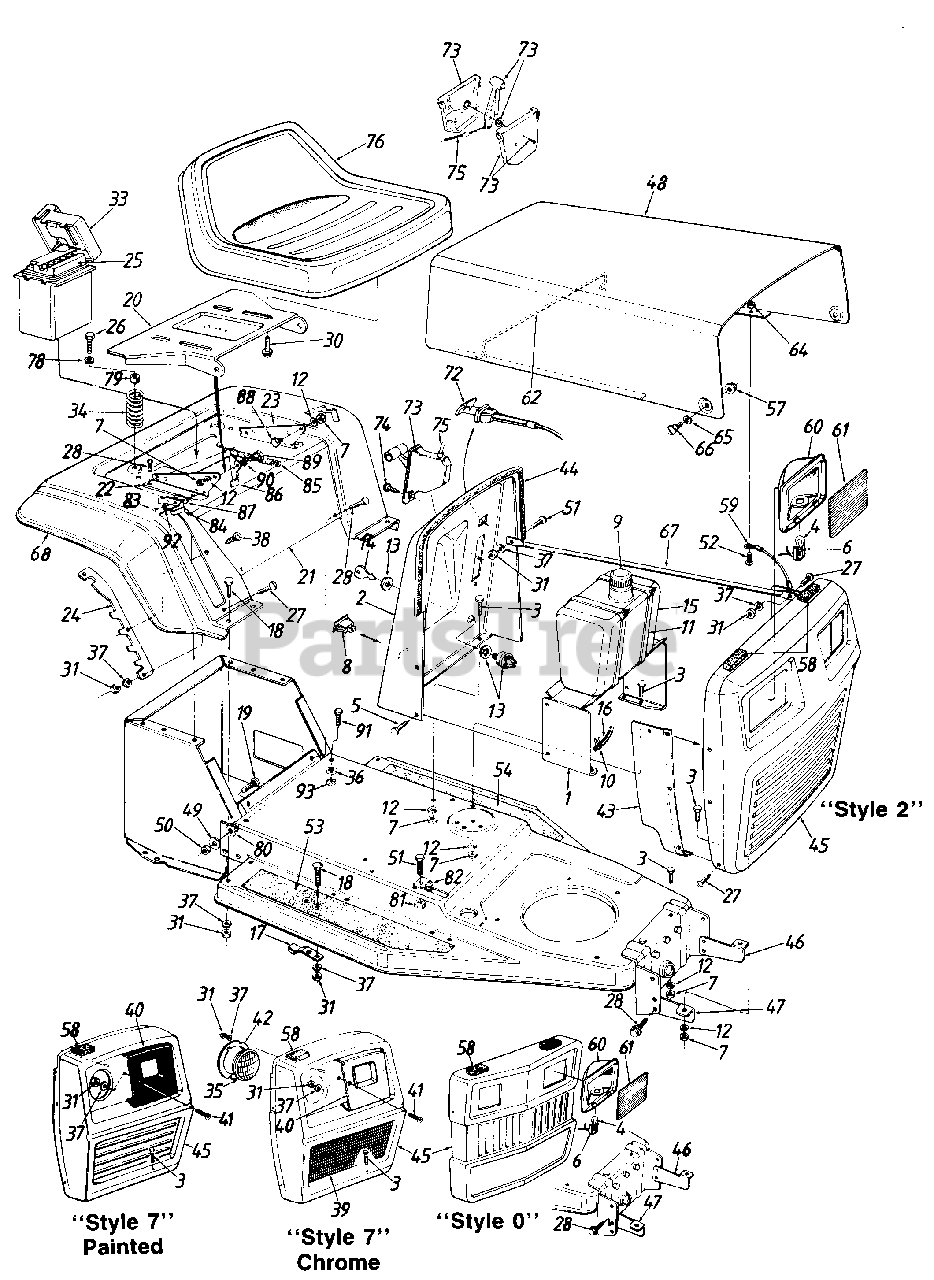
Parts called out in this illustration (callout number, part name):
1	Dash Panel Support Brkt.
4	Bulb
5	Hex AB-Tap Scr. 1/4 x .62"
6	Socket
7	Hex Nut 5/16-18 Thd.*
8	Light Switch
9	Gas Gauge
10	Hose Clamp
11	Cable Tie
12	L-Wash. 5/16" I.D.*
13	Ignition Switch
14	Ignition Key
15	Fuel Tank
16	Gas Line 24" Long
17	Blade Brake Ass'y.
18	Carriage Bolt 1/4-20 x .62"
19	Ribbed Neck Bolt 3/8-24 x .8"
20	Seat Pivot Brkt.
21	Rear Fender
22	Seat Hinge Support Brkt.-R.H.
23	Seat Hinge Support Brkt.-L.H.
24	Deck Lift Index Brkt.
25	Battery
26	Hex Self-Tap Screw 5/6-18 x 1.25" Lg.
27	Truss Mach. Scr. 1/4-20 x .75" Lg.
28	Hex AB-Tap Scr. 5/16 x .75" Lg.
30	Hex Self-Tap Scr. 3/8-16 x .75" Lg.
31	Hex Nut 1/4-20 Thd.*
33	Battery Box w/Cover
34	Compression Spring
35	Headlight
36	Bell-Wash. 5/16" I.D.
37	L-Wash. 1/4" I.D.*
38	Truss Wash. Hd. Tap Scr. #10 x .5" Lg.
39	Grille Insert
40	Bezel
41	C-Sunk Mach. Scr. 1/4-20 x 1.5"
42	Headlight Retainer
43	Side Panel-R.H.
44	Trim Strip 31" Lg.
46	Grille Mtg. Brkt.-L.H.
47	Grille Mtg. Brkt.-R.H.
50	Hex L-Nut 3/8-24 Thd.
51	Hex Bolt 1/4-20 x .62" Lg.
52	Truss Mach. Scr. #10-24 x .5" Lg.
53	Foot Pad-R.H.
54	Foot Pad-L.H.
57	Lock Nut 1/4-28 Thd.
58	Foam Strip
59	Hood Stop
60	Headlight Housing
61	Lens
62	Hood Spring
64	Hex Sems Nut #10-24 Thd.
65	Spr. Wash. .39" I.D. x .62" O.D.
66	Shld. Bolt
67	Grille Support
68	Trim Strip 81" Lg.
72	Choke Control
73	Throttle Control Box
74	Truss AB-Tap Scr. #10 x .5"
75	Throttle Wire
76	Seat Assembly
78	Flat Wash. .344" I.D. x .88" O.D.
79	Bushing
80	Clamp
81	Hex L-Nut 1/4-20 Thd.
82	Clamp
83	Hex Tap Scr. #8 x .5" Lg.
84	Spring Switch
85	Ext. Spring 5.31" Lg.
86	Seat Lift Brkt.
87	Insulator Nut Plate
88	Shld. Bolt .437" Dia. x .162" Lg.
89	Shld. Bolt .437" Dia. x .268" Lg.
90	Spr. Wash. .445" I.D. x .75" O.D.
91	Hex Bolt 5/16-24 x .75" Lg.
92	Fiber Washer
93	Hex Nut 5/16-24 Thd.
